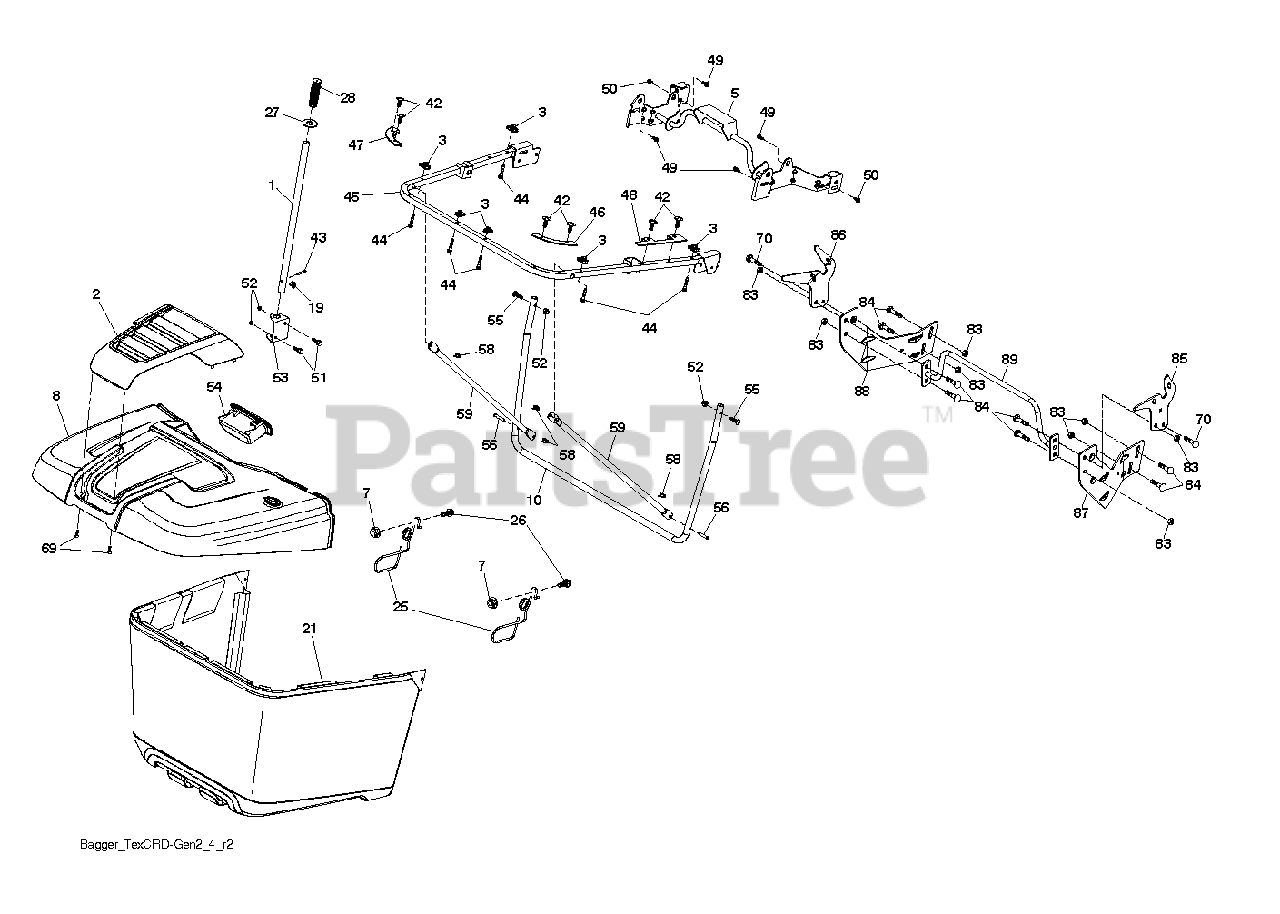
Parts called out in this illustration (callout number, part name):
1	TUBE.HANDLE.BAGGER.CRD/SRD.BLA
2	APPLIQUE.BAGGER
3	1/4-20 U NUT
5	FRAME TEX_CRD_GEN2 UPPER PIVOT
7	NUT T
8	BAGGER TOP
10	FRAME TEX_CRD_GEN2 BAGGER FRAM
19	PIN.COTTER.5/16.BOW TI
21	BAG FRAME BAGGER ASSEMBLY. HUS
25	LATCH LATCH. BAG. CRD GEN 2
26	SCREW HEX CRT
27	GROMMET RUBBER GROMMET, DUMP T
28	GRIP.HANDLE.BLACK
42	CLIP CHRISTMAS TREE CLIP
43	RIVET,DRILLED
45	FRAME TEX_CRD_GEN2 UPPER U FRA
46	CONNECTOR RIGHT BAGGER CORNER
47	CONNECTOR LEFT BAGGER CORNER C
48	BAFFLE BAGGER SIDE CLOSE-OUT
49	BOLT, SHOULDER 5/16-18
50	BOLT, 5/16-18 X 1 3/4
51	BOLT.CARR.SQNK.5/16-18UNC.X3/4
52	NUT.71038.31-18.HEX.NYLOCK
53	BRACKET DUMP HANDLE BRACKET, T
54	HANDLE BAGGER TOP FRONT HANDLE
55	BOLT
56	PIN.CLEVIS.183
58	RETAINER CLIP PM
59	TUBE BAGGER SPREADER TUBE, TEX
69	SCREW,#8.FLAT.HEAD.DRILL.TIP
70	SCREW, 3/8-16X3/4
83	NUT
84	BOLT D
85	BRACKET.RH.PIVOT.MAN.DUMP.BLAC
86	BRACKET.LH.PIVOT.MAN.DUMP.BLAC
87	BRACKET.RH.MID.SUP.BAG.TEX.CRD
88	BRACKET.LH.MID.SUP.BAG.TEX.CRD
89	TUBE.WELD.OFSET.STRUT.BAG.X431
